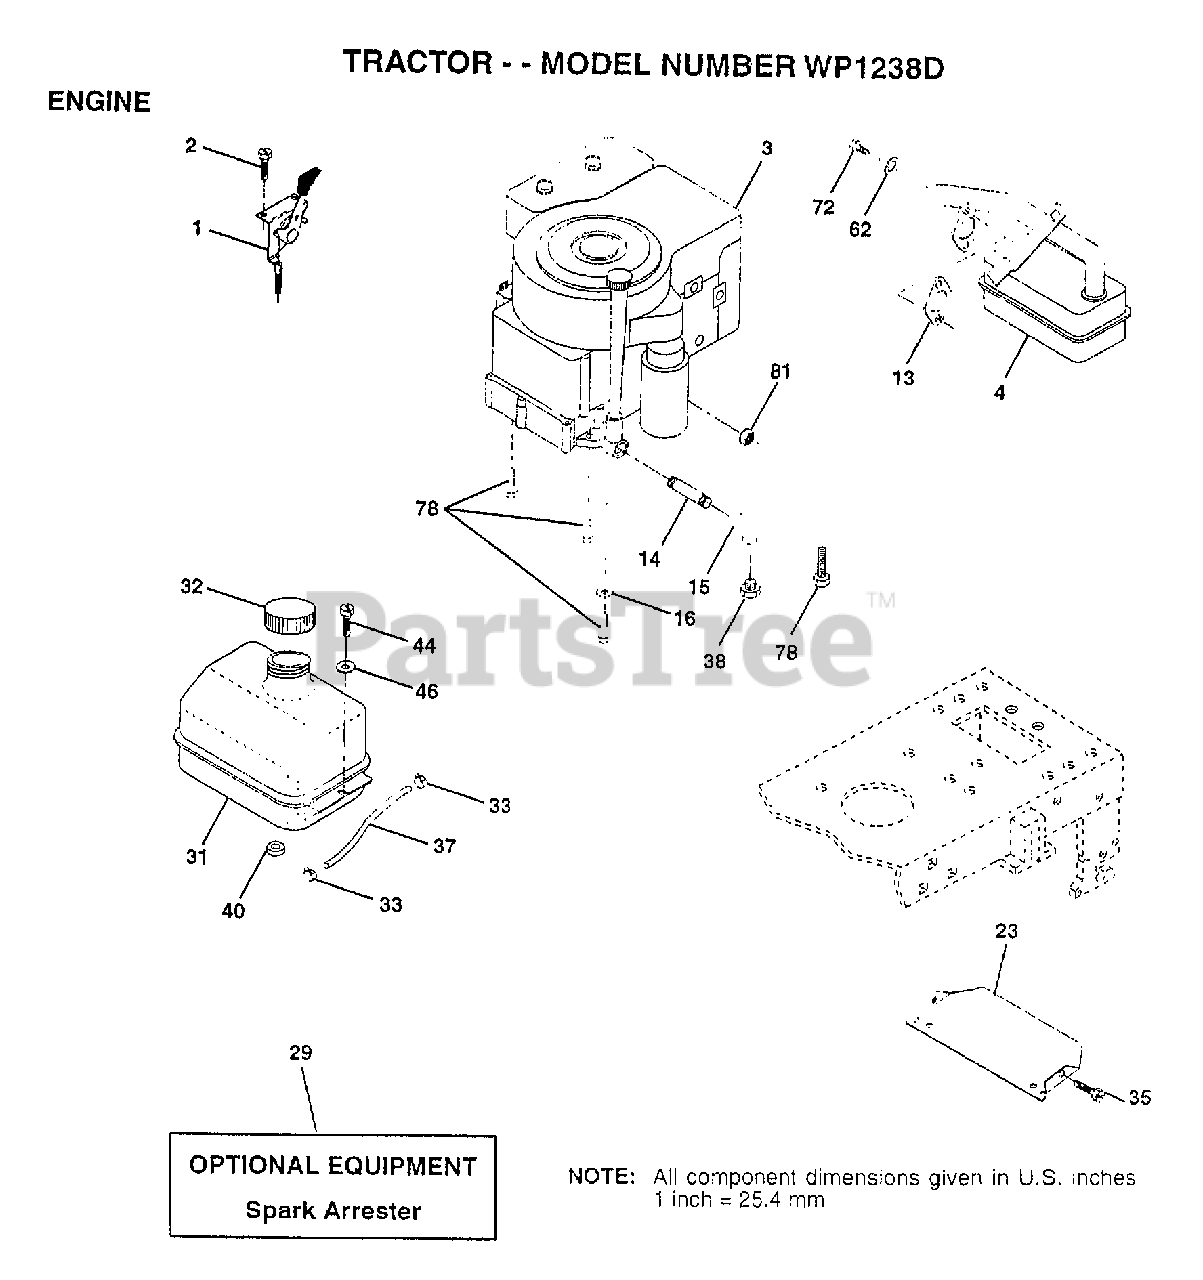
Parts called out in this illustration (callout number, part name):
1	THROTTLE CONTROL
2	SCREW LT
4	MUFFLER
13	GASKET ENG 1 313 LD TIN PLATED
14	PIPE NIPPLE
15	ELBOW
16	LOCKWASHER
23	SHIELD-HEAT
31	TANK.FUEL.LT.
32	CAP ASM FUEL
33	HOSE CLAMP
35	SCREW
37	LINE FUEL
44	SCREW HEX CRT
46	WASHER
62	LOCKWASHER
72	SCREW
78	SCREW
81	NUT
